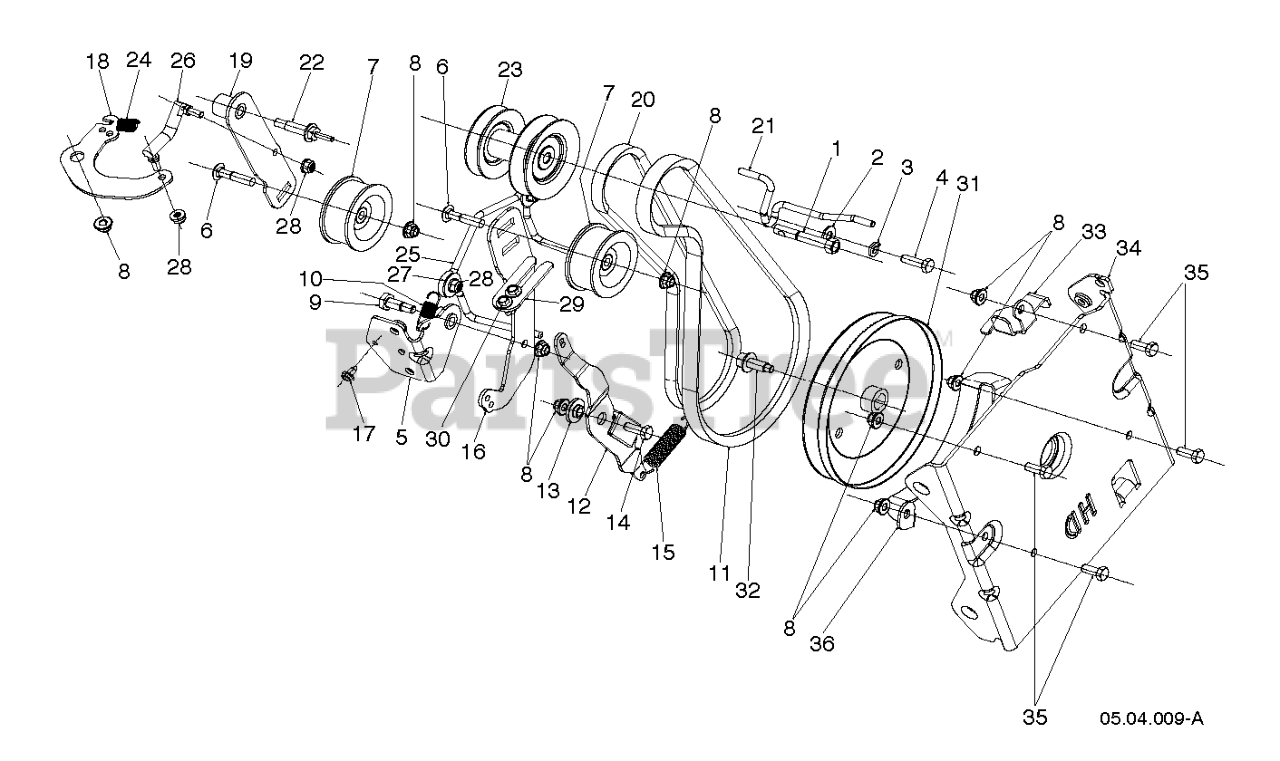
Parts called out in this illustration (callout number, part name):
1	BOLT.ENGINE.PULLEY
2	WASHER 11/32 X 11/16 X 14 GA T
3	WASHER SPRING LOCK WASHER WITH
5	BRACKET WELDMENT, IDLER ARM ZI
6	BOLT 5/16-18 CARRIAGE 1.5L
7	PULLEY IDLER
8	NUTNYLOK.FLRANGE.5/16-18
9	SCREW HEX HEAD SHOULDER
10	SPRING IDLER RETURN
11	BELT 5L 39.15L
12	ARM IMPELLER BRAKE
13	BUSHING.BRAKE.ARM
14	BOLT HEXAGON BOLT 5/16-18 X 7/
15	SPRING EXTENSION - BRAKE
16	ARM IDLER BLACK ZINC
18	Bell Cranks
19	ARM DRIVE IDLER BLACK ZINC PLA
20	BELT 4L DRIVE
21	GUIDE BELT - 4L HYDRO, 5L IMPE
22	GUIDE BELT, SHOULDER SCREW
23	PULLEY WELDMENT
24	SPRING EXTENSION - DRIVE
25	GUIDE BELT - HYDRO 2 WITH FAN
26	LINK ASSY DRIVE IDLER
28	NUT FLG, NYLOCK, 1/4-20 GR G C
30	HEX.WASHER.HEAD 1/4-20 X .65
31	PULLEY IMPELLER DD 5L HD
32	SCREW HEXAGON HEAD FLANGE 3/8-
34	BRACKET AUGER HOUSING INTERFAC
35	SCREW HEXAGON HEAD SCREW 5/16-
36	BRACKET.BELT.KEEPER.LOWER.BLAC
